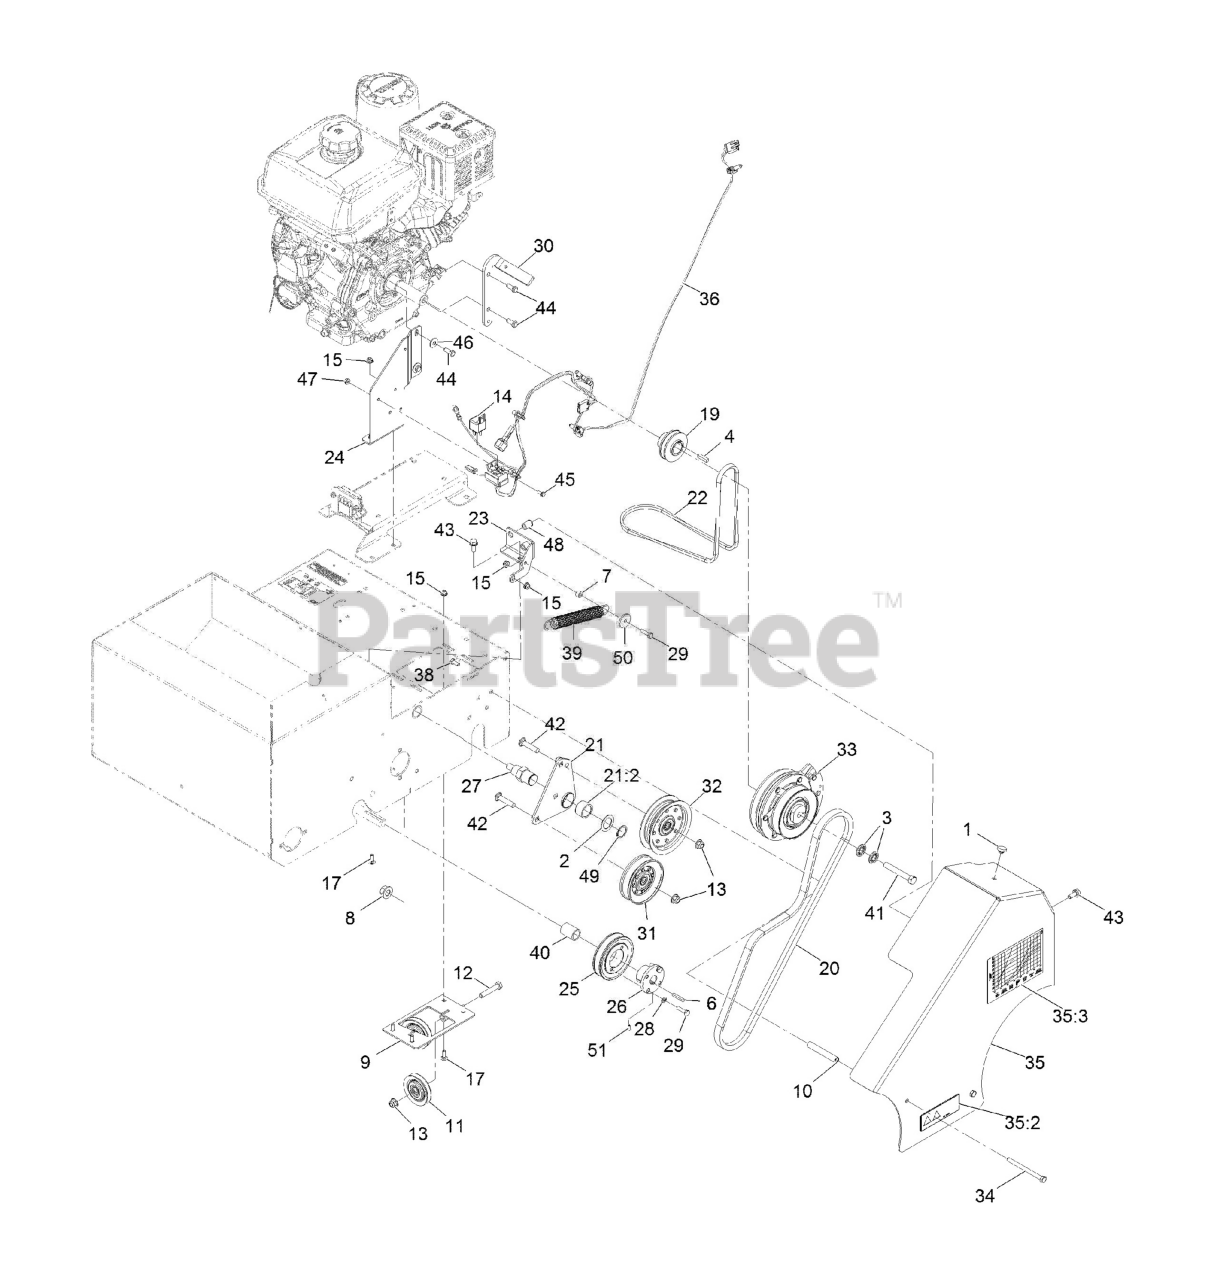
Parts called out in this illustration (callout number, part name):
2	WASHER-SPACER
3	WASHER-SPRING
6	KEY-SQUARE
8	Nut-Lock 1/2-13
9	PULLEY-TENSION
10	SPACER-KICKSTAND, LONG
11	PULLEY-IDLER
12	SCREW-HH
13	NUT-HF, NI
17	BOLT-CARR
19	PULLEY-MULE DRIVE
20	BELT-SEEDER, CLUTCH
21	IDLER ARM ASM
21:2	BUSHING
22	BELT-MULE DRIVE
23	BRACKET-SPRING
24	GUARD-BELT
25	SHEAVE-TAPER LOCK
26	BUSHING-TAPER LOCK
27	PIVOT-IDLER
28	WASHER-LOCK
29	SCREW-HH
30	STOP-CLUTCH
31	PULLEY-IDLER V
32	PULLEY-IDLER FLAT (4.06-I
33	CLUTCH-ELECTRIC
34	SCREW-HH
35	BELT GUARD ASM
35:2	DECAL-DANGER
35:3	DECAL-GRAPH, SEED
36	HARNESS-WIRE
38	SCREW-HH
39	SPRING-EXTENSION
41	SCREW-HH
42	SCREW-CARR
43	SCREW-HHF
44	SCREW-HH
45	SCREW-HWH
46	WASHER-BELLEVILLE
47	NUT-LOCK, FLANGE
48	NUT-CLINCH
49	RING-RETAINING
50	WASHER
51	SCREW-SET, HS
